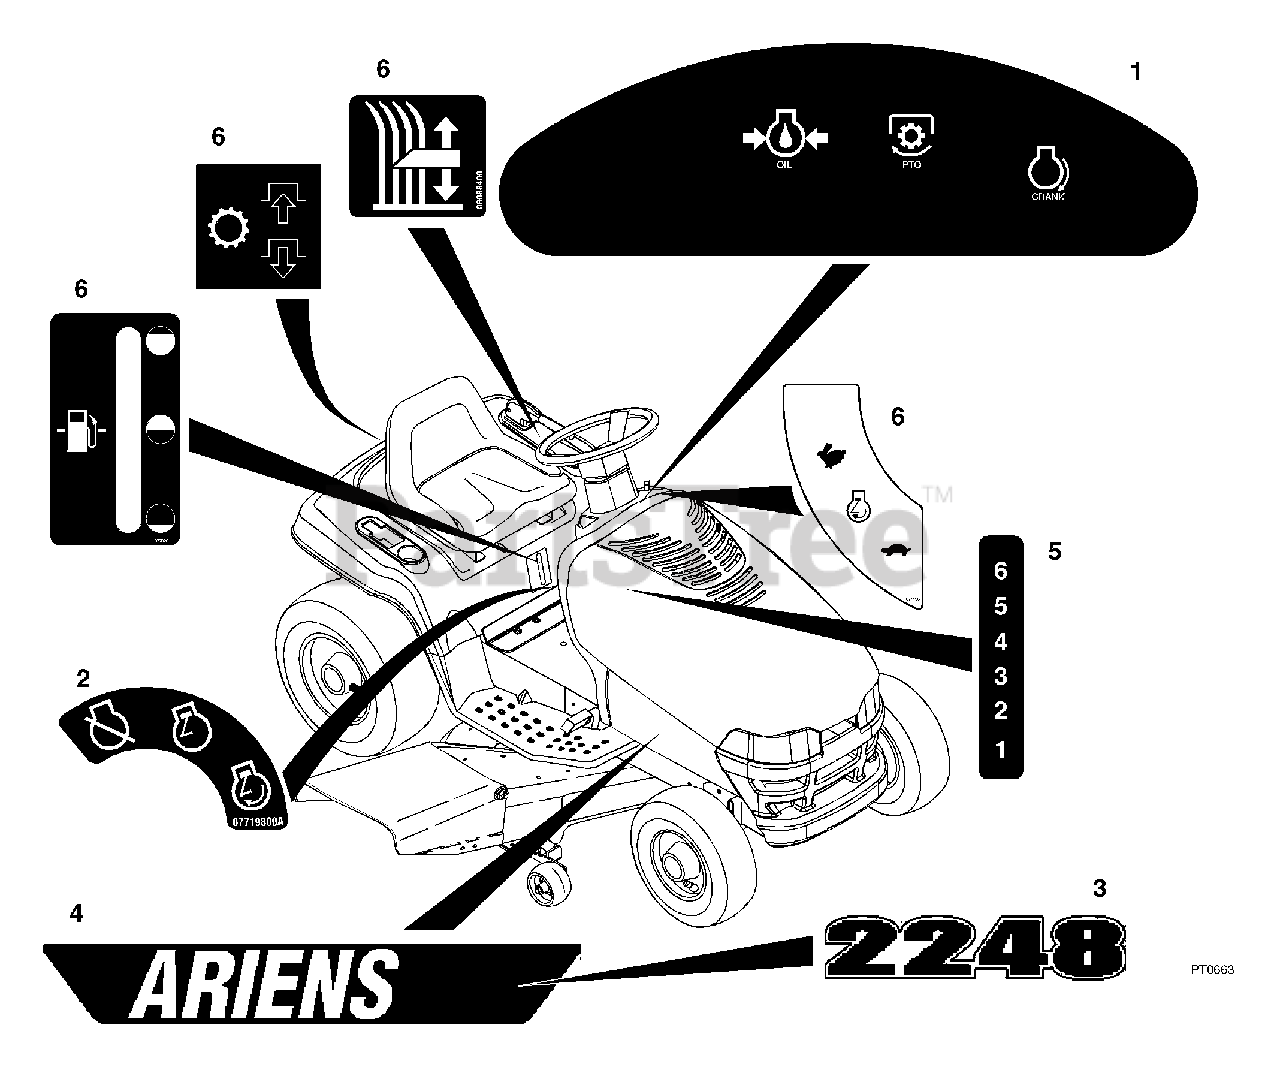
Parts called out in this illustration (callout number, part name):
1	DECAL - DASH W/LIGHTS
2	DECAL - IGNITION
3	DECAL- HOOD YT 2248
4	DECAL-HOOD YT ARIENS
5	DECAL, INDICATOR
6	SET-YT CONTROLS
